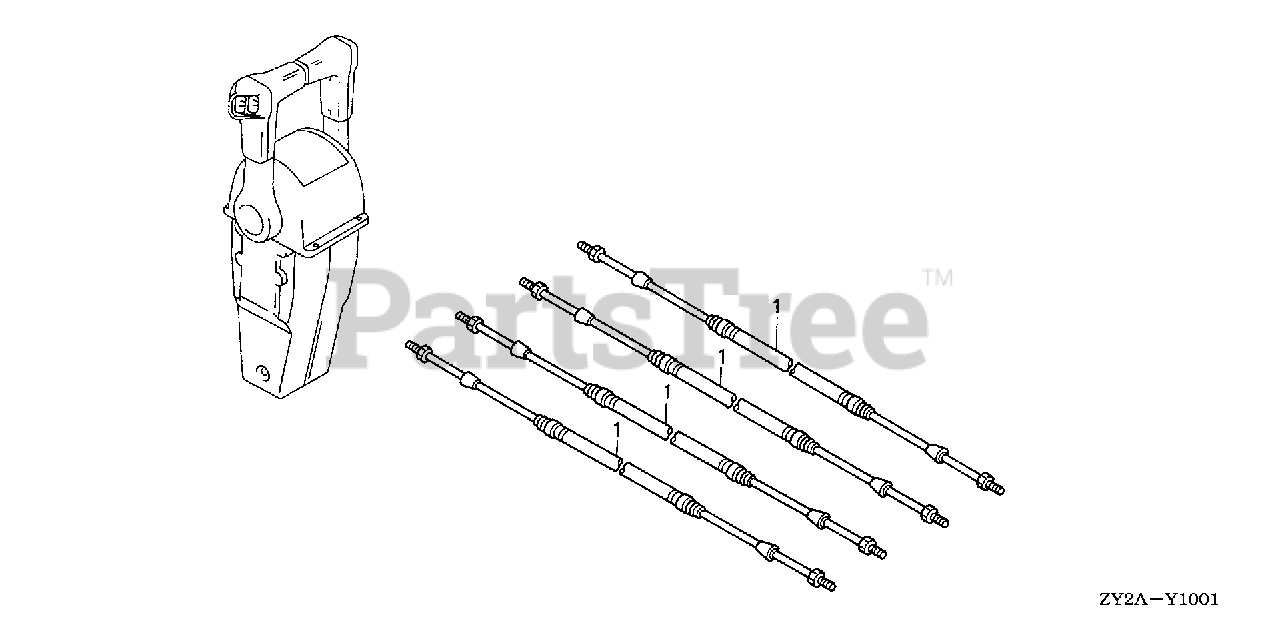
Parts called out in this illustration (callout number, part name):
1	CABLE, REMOTE CONTROL (10') (LOW FRICTION)
1	CABLE ASSY., PUSH-PULL (33C-5FT)
1	CABLE, REMOTE CONTROL (11') (LOW FRICTION)
1	CABLE ASSY., PUSH-PULL (33C-6FT)
1	CABLE, REMOTE CONTROL (12') (LOW FRICTION)
1	CABLE ASSY., PUSH-PULL (33C-7FT)
1	CABLE, REMOTE CONTROL (13') (LOW FRICTION)
1	CABLE ASSY., PUSH-PULL (33C-8FT)
1	CABLE, REMOTE CONTROL (14') (LOW FRICTION)
1	CABLE ASSY., PUSH-PULL (33C-9FT)
1	CABLE, REMOTE CONTROL (15') (LOW FRICTION)
1	CABLE ASSY., PUSH-PULL (33C-10FT)
1	CABLE, REMOTE CONTROL (16') (LOW FRICTION) (NOT AVAILABLE)
1	CABLE ASSY., PUSH-PULL (33C-11FT)
1	CABLE, REMOTE CONTROL (17') (LOW FRICTION)
1	CABLE ASSY., PUSH-PULL (33C-12FT)
1	CABLE, REMOTE CONTROL (18') (LOW FRICTION) (NOT AVAILABLE)
1	CABLE ASSY., PUSH-PULL (33C-13FT)
1	CABLE, REMOTE CONTROL (19') (LOW FRICTION)
1	CABLE ASSY., PUSH-PULL (33C-14FT)
1	CABLE, REMOTE CONTROL (20') (LOW FRICTION) (NOT AVAILABLE)
1	CABLE ASSY., PUSH-PULL (33C-15FT)
1	CABLE, REMOTE CONTROL (21') (LOW FRICTION)
1	CABLE ASSY., PUSH-PULL (33C-16FT)
1	CABLE, REMOTE CONTROL (22') (LOW FRICTION) (NOT AVAILABLE)
1	CABLE ASSY., PUSH-PULL (33C-17FT)
1	CABLE, REMOTE CONTROL (23') (LOW FRICTION)
1	CABLE ASSY., PUSH-PULL (33C-18FT)
1	CABLE, REMOTE CONTROL (24') (LOW FRICTION) (NOT AVAILABLE)
1	CABLE ASSY., PUSH-PULL (33C-19FT)
1	CABLE, REMOTE CONTROL (25') (LOW FRICTION)
1	CABLE ASSY., PUSH-PULL (33C-20FT)
1	CABLE, REMOTE CONTROL (26') (LOW FRICTION)
1	CABLE ASSY., PUSH-PULL (33C-21FT)
1	CABLE, REMOTE CONTROL (27') (LOW FRICTION)
1	CABLE ASSY., PUSH-PULL (33C-22FT)
1	CABLE, REMOTE CONTROL (28') (LOW FRICTION) (NOT AVAILABLE)
1	CABLE ASSY., PUSH-PULL (33C-23FT)
1	CABLE, REMOTE CONTROL (29') (LOW FRICTION)
1	CABLE ASSY., PUSH-PULL (33C-24FT)
1	CABLE, REMOTE CONTROL (30') (LOW FRICTION) (NOT AVAILABLE)
1	CABLE ASSY., PUSH-PULL (33C-25FT)
1	CABLE, REMOTE CONTROL (31') (LOW FRICTION)
1	CABLE ASSY., PUSH-PULL (33C-26FT)
1	CABLE, REMOTE CONTROL (32') (LOW FRICTION) (NOT AVAILABLE)
1	CABLE ASSY., PUSH-PULL (33C-27FT)
1	CABLE, REMOTE CONTROL (33') (LOW FRICTION)
1	CABLE ASSY., PUSH-PULL (33C-28FT)
1	CABLE, REMOTE CONTROL (34') (LOW FRICTION) (NOT AVAILABLE)
1	CABLE ASSY., PUSH-PULL (33C-29FT)
1	CABLE, REMOTE CONTROL (35') (LOW FRICTION)
1	CABLE ASSY., PUSH-PULL (33C-30FT)
1	CABLE ASSY., PUSH-PULL (33C-31FT)
1	CABLE ASSY., PUSH-PULL (33C-32FT)
